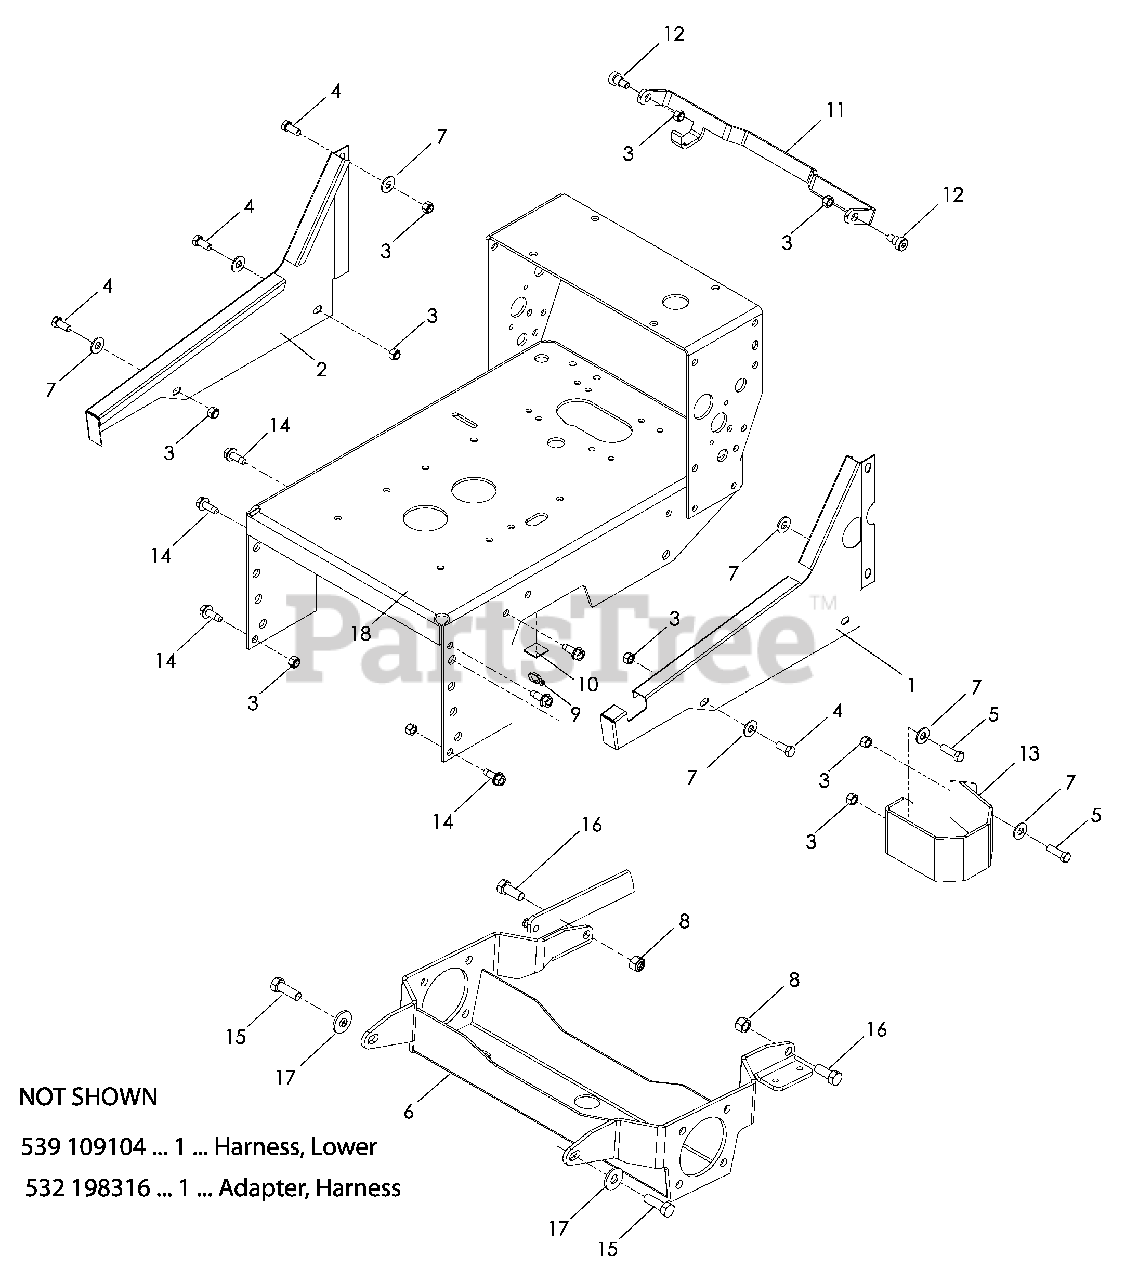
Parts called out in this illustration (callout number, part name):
1	PANEL, SIDE, RH
2	PANEL, SIDE, LH
3	NUT 3/8-16 HEX NYLOC
4	Hcs3/8-16 x 7/8
5	HCS 3/8-16 x 1¼
6	AXLE, HYDRO
7	WASHER 3/8 FLAT
8	NUT ½ HEX NYLOC
10	MOUNTING BLOCK
11	BAR, THROW OUT
12	SB 3/8-16 x 3/8 SKT HD
13	GUARD, FILTER
14	BOLT 3/8-16 x 1 THD FRM
15	HCS ½-13 x 1½
16	HCS ½-13 x 1¼
17	WASHER ½ FLAT
18	ENGINE DECK W/DECAL
